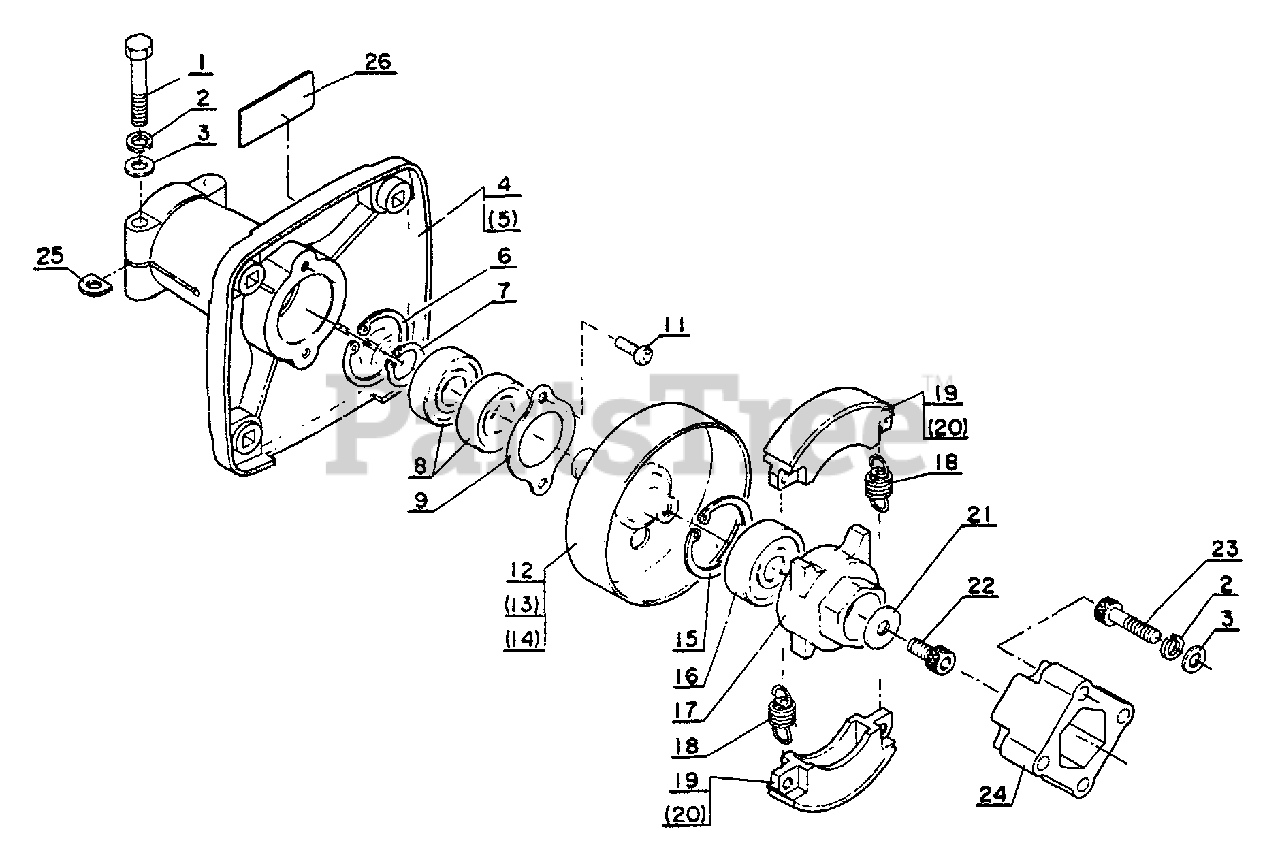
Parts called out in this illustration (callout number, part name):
1	BOLT - 5X30
2	LOCKWASHER - 5
3	WASHER - 5
4	CASE, CLUTCH
6	RING, RETAINING - 28
7	RING, RETAINING - 12
8	BEARING, BALL - 6001 DDU
9	RETAINER
11	SCREW - 4X10
12	DRUM, CLUTCH
15	RING, RETAINING - 30
16	BEARING, BALL - 6200
17	HUB, CLUTCH
18	SPRING, CLUTCH
19	SHOE, CLUTCH
21	WASHER - 5
22	SCREW - 5X12
23	SCREW - 5X25
24	COUPLING
